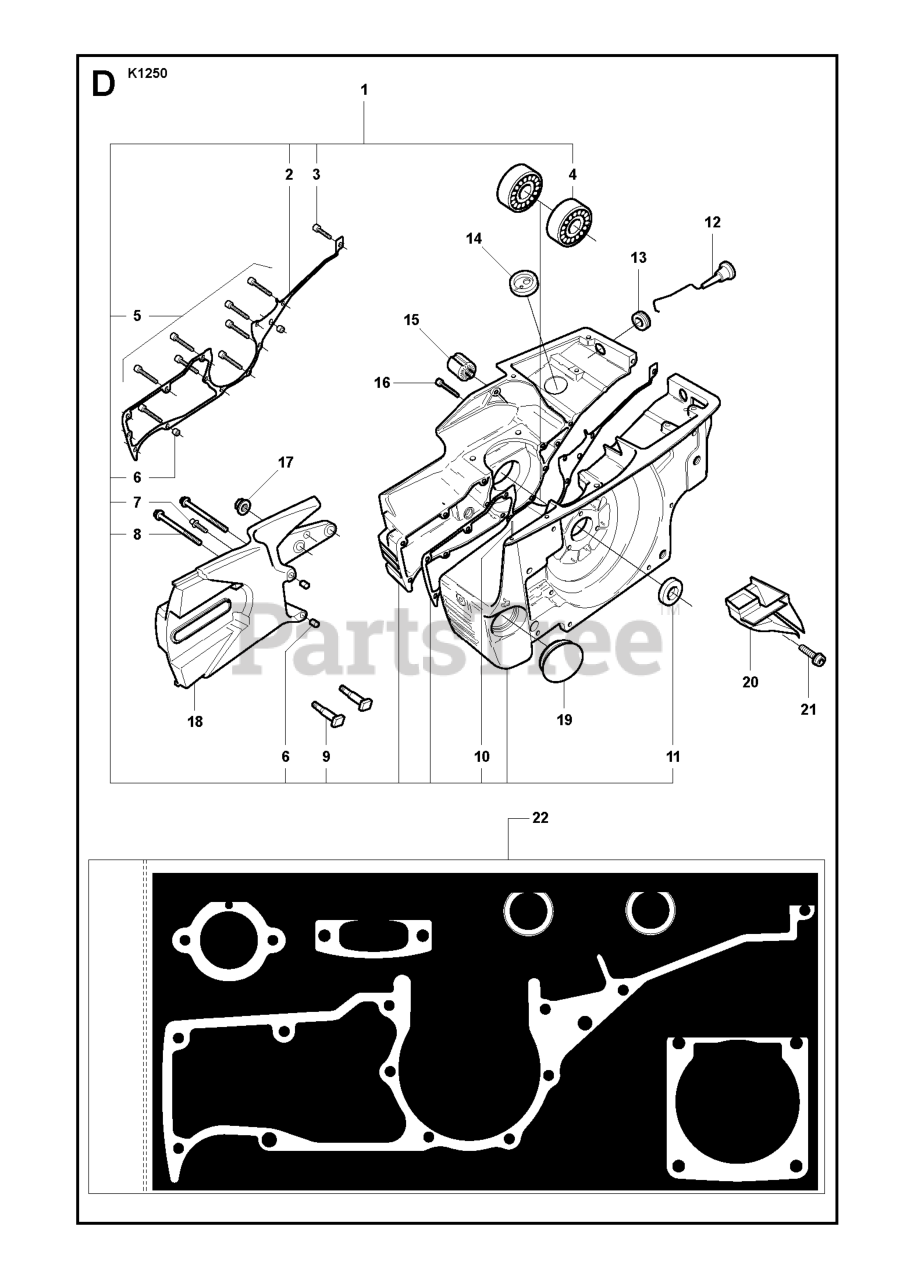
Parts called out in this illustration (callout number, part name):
2	CRANKCASE GASKET
3	SCREW MC6S 5X20
4	BALL BEARING 6203C3QE6
5	SCREW MC6S 5X40
11	SEALING RING
12	CHOKE CONTROL
15	ANTIVIBE ELEMENT
16	SCREW MC6S 6X20
17	NUT M8 FLANGE
18	ARM
21	SCREW
22	GASKET SET
23	RP GASKET
24	RP GASKET
